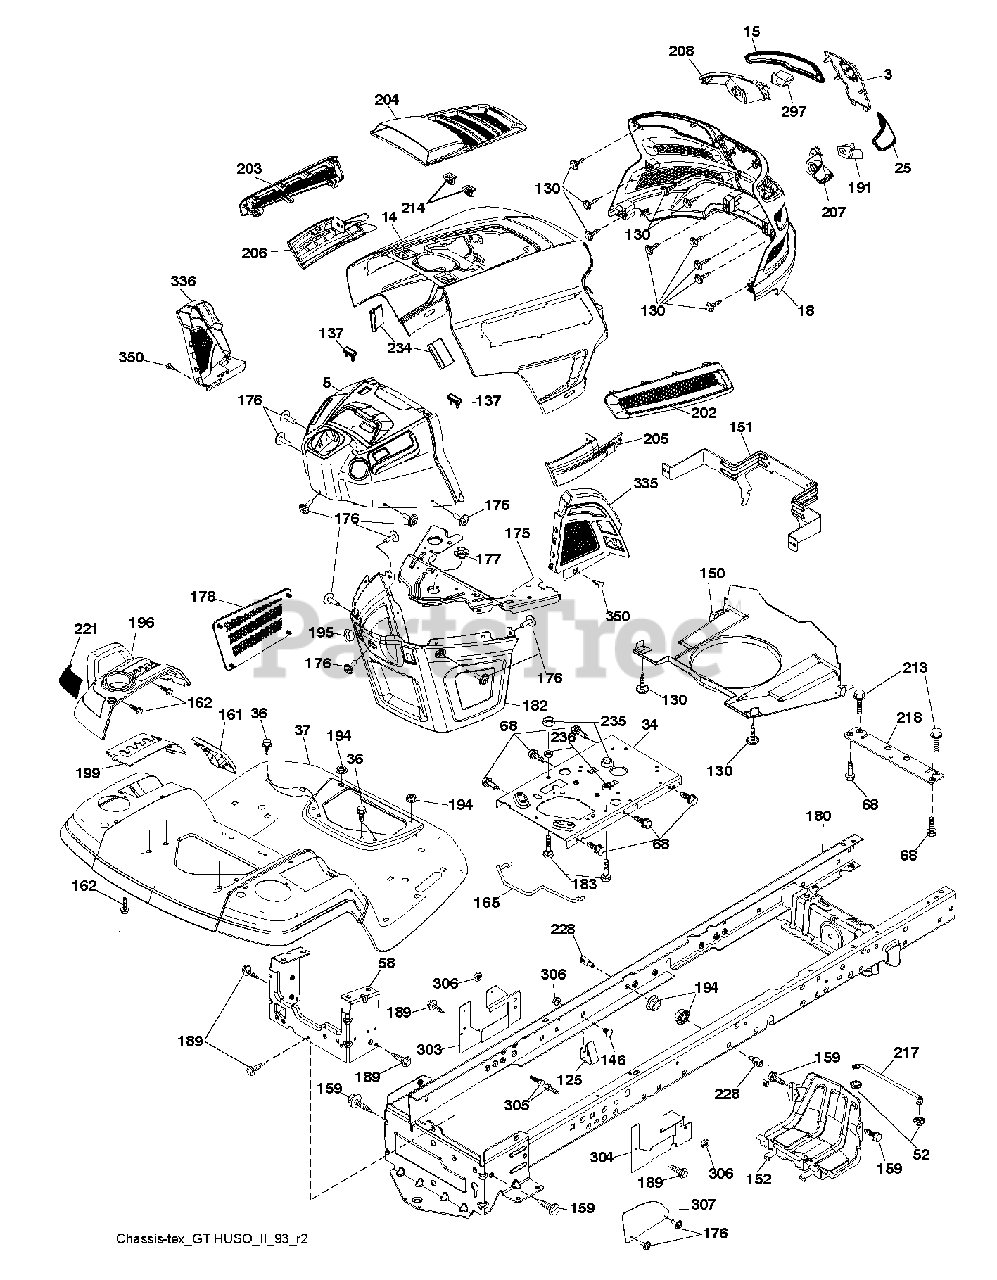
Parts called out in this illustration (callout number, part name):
3	APPLIQUE.SUBASM.GT.HUSQ.II
5	GT2.DASH.UPPER.W/BUMPERS
14	HOOD.ASM.HUSQVARNA.GT.TEX.ORAN
15	LENS.HEADLIGHT.LH.GTII.2011
18	GRILLE.SUBSTRATE.2011.
25	LENS.HEADLIGHT.RH.GTII.2011
34	PLATE.ENGINE.WELDED.CHASSIS
36	SCREW 5/16"
37	FENDER.PNT.TX.GT.CH/FW/DL.HUSQ
52	LOCKNUT
58	DRAWBAR.UPPER.2PC,LRG.FENDER
68	SCREW LT
125	CLIP.FUEL.LINE
130	SCREW.#10 X 0.750.BOS
137	BUMPER DASH
146	BOLT.RDHD.SHT.SQNK.3/8-16X5/8
150	AIR.DUCT.GTV.BLACK
151	BRACKET.PIVOT.HOOD.GT.HUSQ.II
152	SHIELD.BROWNING.PNT.GT.V2
159	SCREW, 3/8-16X3/4
161	CONSOLE.WINDOW.FUEL.HUSQ.GT
162	SCREW.HI-LO.CONSOLE
165	SUPPORT.TANK.REAR.W/TEX
175	PLATE.CROSSMEMBER.HUSQ
176	SCREW.#10-24X5/8.RN.QU
177	BUSHING, STEERING
178	CARGO.ASM.NET.TXGT.W/C
180	CHASS.WLDMNT.TLT.12GA/2PC.20"
182	DASH.LOWER.COMMON.12V.ADAPTOR
183	BOLT.5/16-18X1-1/4 FULL THD
189	SCREW
191	INSERT.REFLECTIVE.RH.HUSQ.GTII
194	NUT LOCK HEX FLANGE 5/16-18
195	PLUG.HOLE.DASH.LOWER.12V.BLK
196	SUBASM.CONSOLE.HUSQ.GT.DECKLFT
199	PLATE.DECK.LIFT.HUSQVARNA.GT
202	VENT.SIDE.RH.GT.HUSQ.II.
203	VENT.SIDE.LH.GT.HUSQ.II.498
204	VENT.TOP.HUSQ.GT2
205	SIDE.TRIM.RH.GT.HUSQ.II
206	SIDE.TRIM.LH.GT.HUSQ.II.GRAY
207	BEZEL LIGHT.RH.GT.II.MYLAR
208	BEZEL LIGHT.LH.GT.II.MYLAR
213	BOLT
214	CLIP.RETAINER.TINNER.
217	ROD.PIVOT.HOOD
218	X-PIECE.HOOD.STOP.NON/
221	REFLECTOR.LH.TEX GT HU
228	STUD.FASTNER.W/ANTI-ROTATE
234	BUMPER.HOOD.TEX.HUSQVARNA
235	SPACER FENDER
236	NUT.CENTERLOCK.5/16-
297	INSERT.REFLECTIVE.LH.HUSQ.GTII
303	SHIELD CHASSIS LEFT
304	SHIELD CHASSIS RIGHT
306	NUT LOCK FLG 3/8-16 UNC
307	SHIELD UPPER PEDAL
335	COVER.LOWER.DASH.RH.BLACK
336	COVER-LH.LOWER.DASH.GT2.BLACK
350	CLIP.X-MAS.TREE
